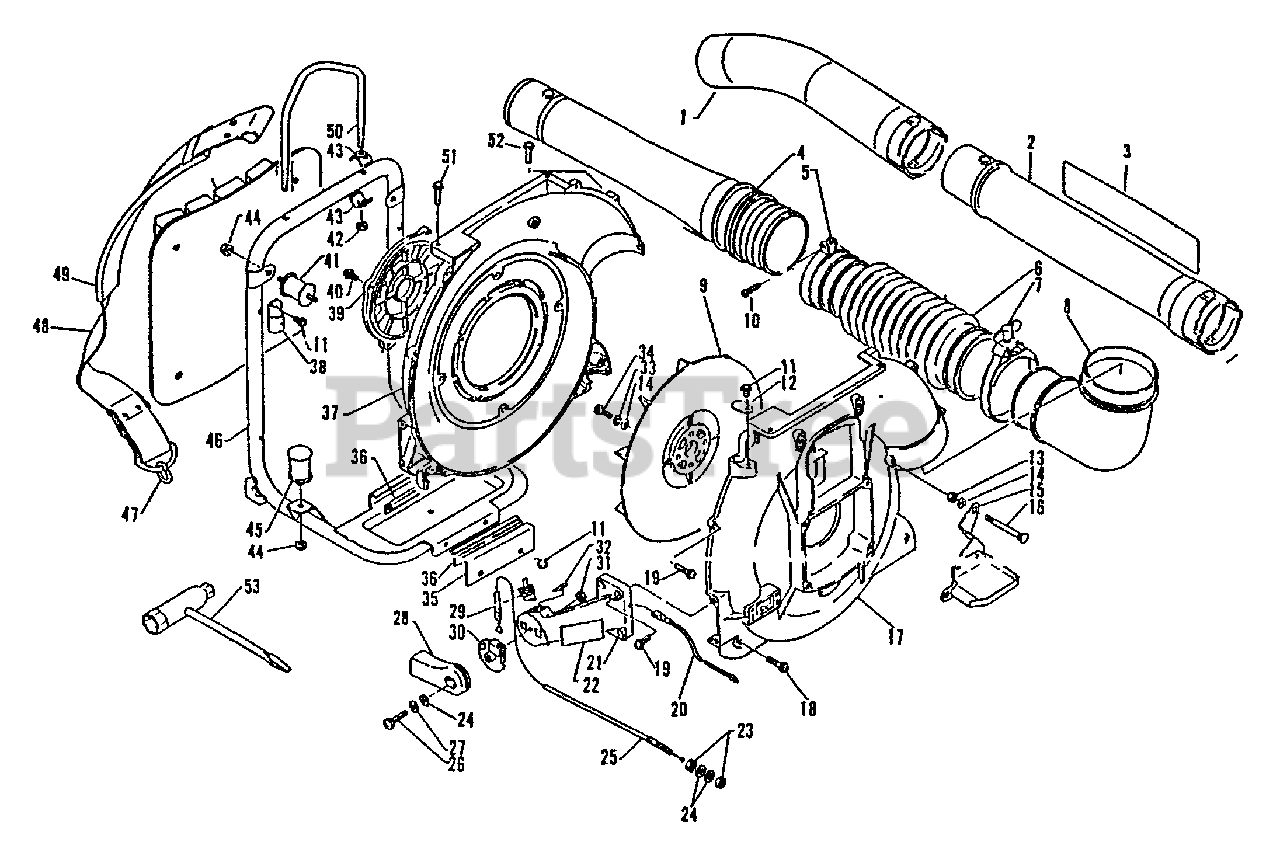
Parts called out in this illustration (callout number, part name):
1	TUBE, BLOWER - CURVED
2	TUBE, BLOWER - STRAIGHT
3	LABEL - LESCO
4	TUBE, BLOWER - SWIVEL
5	CLAMP KIT
6	TUBE, FLEXIBLE
10	SCREW 5×25
11	SCREW 5×10
13	NUT - 5
14	WASHER, FLAT 5.5×10×0.8
15	BRACKET, MUFFLER COVER
17	COVER, FAN - LEFT
18	SCREW 5×25
19	SCREW 5×20
21	BRACKET, THROTTLE LEVER
22	LABEL, CAUTION
25	CABLE, THROTTLE
26	SCREW 6×25
28	CONTROL, THROTTLE
29	IGNITION SWITCH ASSY
31	NUT, HEX M6
32	LABEL, ON-OFF
33	WASHER, SPRING 5
35	BRACKET, FUEL TANK
36	CUSHION, FUEL TANK
37	COVER, FAN - INNER
38	BRACKET, CUSHION
39	SHIELD, DEBRIS
42	LOCKNUT - 6
44	NUT, FLANGE M6
46	FRAME, BACKPACK
47	RING, HARNESS
48	BACKPACK STRAP ASSY
49	CUSHION, BACKPACK
51	SCREW 6×15
52	SCREW 6×20
53	T-WRENCH 10×19 MM
